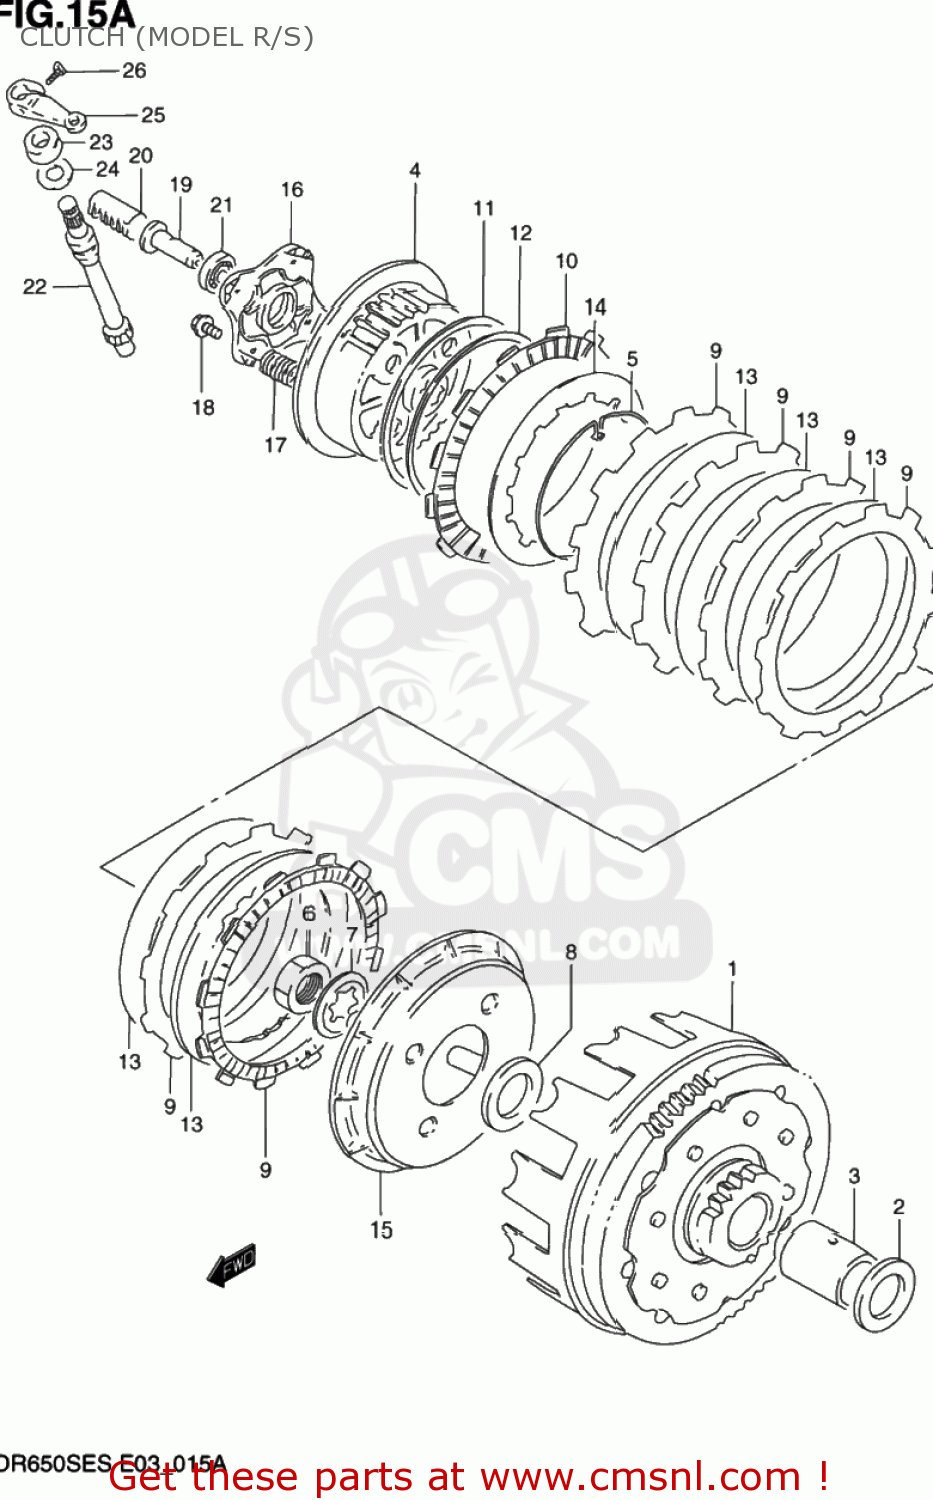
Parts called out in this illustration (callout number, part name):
1	GEAR ASSEMBLY,PRIMARY DRIVE
2	WASHER
3	SPACER(22X28X32.5)
4	HUB,CLUTCH SLEEVE
5	RING,WAVE WASHER STOPPER
6	NUT
7	WASHER,LOCK
8	WASHER
9	PLATE,CLUTCH DRIVE (NAS)
10	PLATE,CLUTCH DRIVE NO (NAS)
11	SEAT,WAVE WASHER
12	WASHER
13	PLATE,CLUTCH DRIVEN(T:1.6) (NAS)
14	PLATE,CLUTCH DRIVEN (NAS)
15	DISC,CLUTCH PRESSURE
16	PLATE,RELEASE
17	SPRING
18	BOLT
19	PIECE,CLUTCH PUSH
20	RACK,CLUTCH RELEASE
21	BEARING(12X28X8)
22	PINION,CLUTCH RELEASE
23	SEAL,OIL (12X22X9)
24	WASHER (14.2X22X1)
25	ARM,CLUTCH RELEASE
26	BOLT
